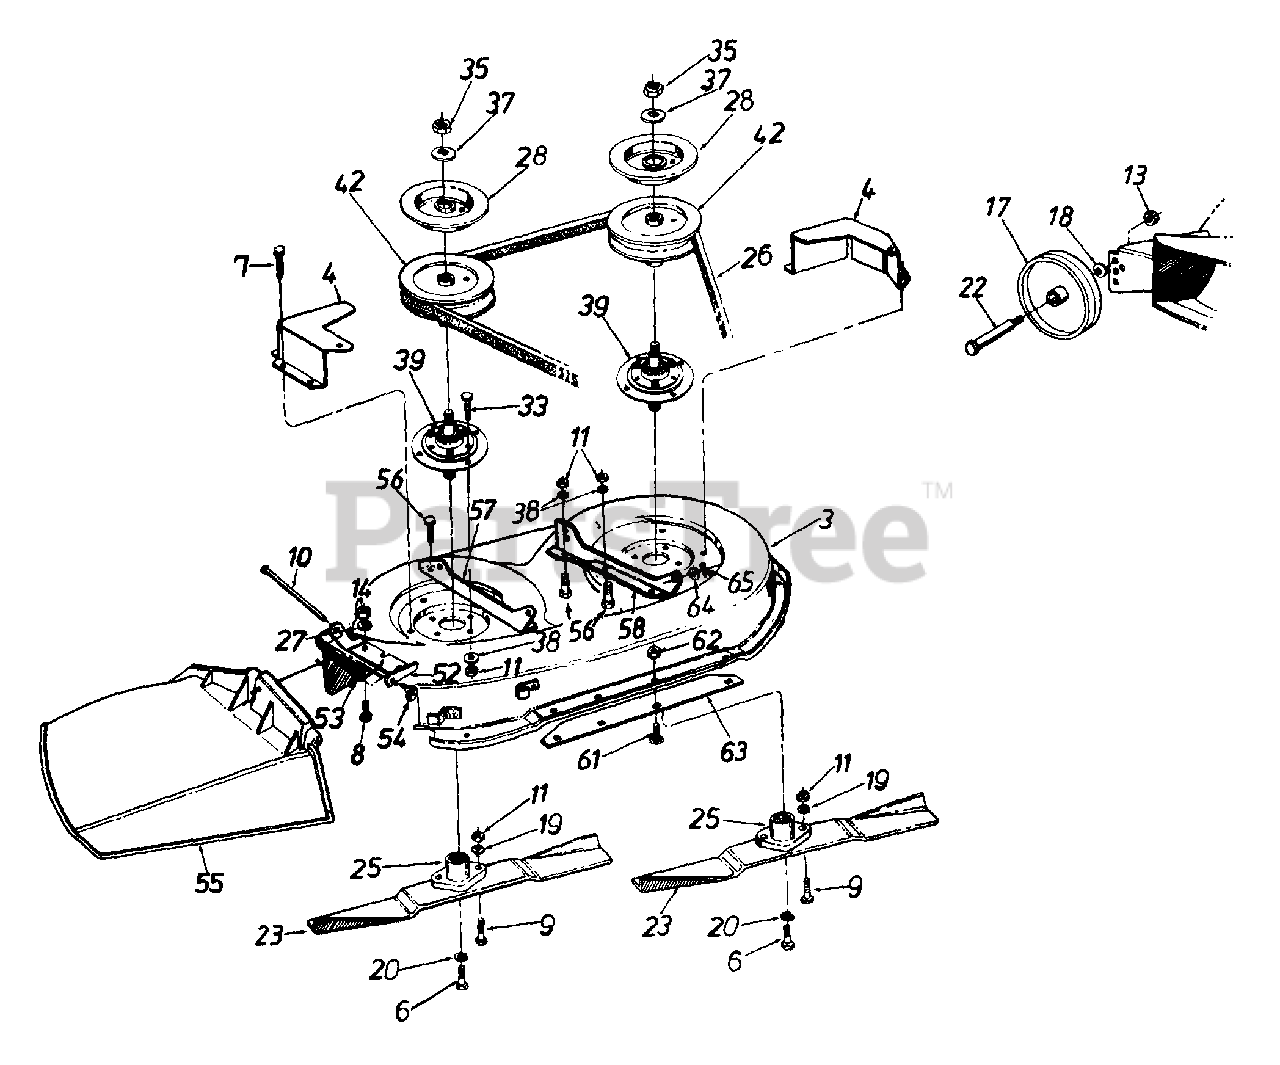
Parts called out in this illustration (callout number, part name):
3	38" Deck Ass'y. w/Deck Wheels
4	Belt Guard Deck
6	Hex Bolt 3/8-24 x 1.0" Lg.
7	Hex Wash. Hd. TT-Tap Scr. 1/4-20 Thd.
8	Hex Bolt 1/4-20 x .62"
9	Hex Bolt Special 5/16-24 x 1.0"
10	Hinge Pin
11	Hex Nut 5/16-24 Thd.
13	Hex Top L-Nut 3/8-16 Thd.
14	Hex Nut 1/4-20 Thd.
17	Deck Wheel - 5"
18	Bell - Wash. .40" I.D. x .88" O.D.
19	L - Wash. 5/16" I.D.
20	L - Wash. 3/8" I.D. - H.D.
22	Shld. Bolt .498" Dia. x 1.53"
23	High - Lift Blade
25	Blade Adapter
26	V - Belt
27	Bell - Wash. 1/4" I.D.
28	Brake Disc
33	Hex Bolt 5/16-24 x .75" Lg.
35	Hex Jam Nut 5/8-18 Thd.
37	L - Wash. 5/8" I.D.
38	Bell - Wash. .345" I.D. x .88" O.D.
39	Blade Spindle Ass'y. Comp.
42	5" Dia. Pulley
52	Hinge Mtg. Brkt.
53	Torsion Spring
54	Push Nut
55	Chute Ass'y. Comp.
56	Hex Bolt 5/16-24 x .75" Lg.
57	Deck Hanger Channel - R.H.
58	Deck Hanger Channel - L.H.
61	Carr. Bolt 1/4-20 x .5" Lg.
62	Hex Sems Nut 1/4-20 Thd.
63	Deck Skirt Ext.
64	Fl - Wash. .406" I.D. x .73" O.D.
65	Hairpin Clip 3/8" Dia.
